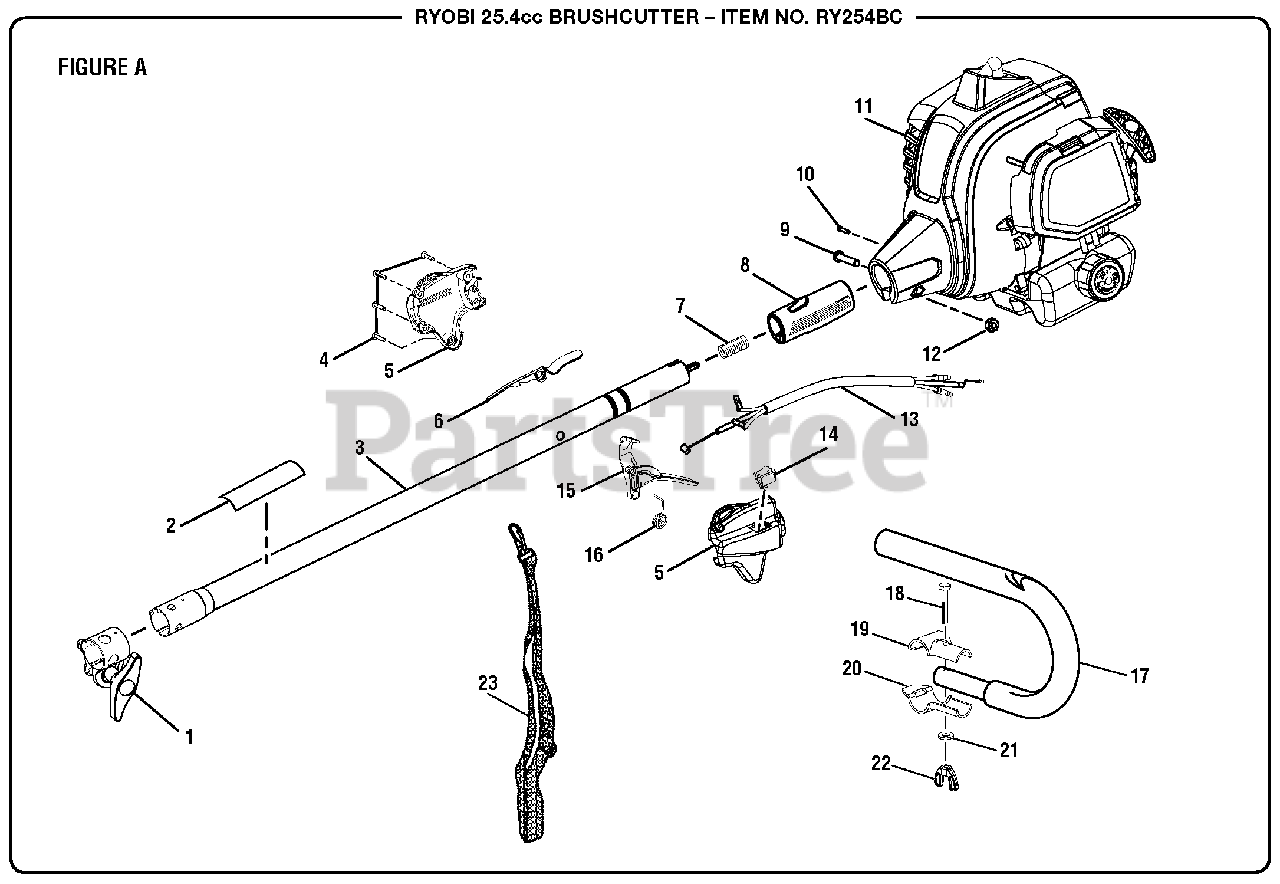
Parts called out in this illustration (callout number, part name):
1	Boom Clamp Assembly
2	Warning Icon Label
3	Upper Boom Assembly
4	Screw (M4 x 20 mm, T20 Torx Hd. S.T.)
5	Control Handle Assembly
6	Trigger Lock
7	Compression Spring
8	Rear Handle Grip
9	Screw (M6 x 30 mm, T27 Torx Button Hd.)
10	Screw (M4 x 8 mm, T20 Torx Pan Hd. S.T.)
11	Powerhead Assembly w/Labels
12	Hex Nut (M6 x 1)
13	Throttle Cable and Wire Assembly
14	On/Stop Switch
15	Trigger
16	Trigger Spring
17	"J" Handle and Grip
18	Bolt (1/4-20 x 1-1/2 in., Hex Hd.)
19	Top "J" Handle Clamp
20	Bottom "J" Handle Clamp
21	Washer (ID7.25 x OD16 x 1.5t)
22	Wing Nut (1/4-20)
23	Shoulder Harness
